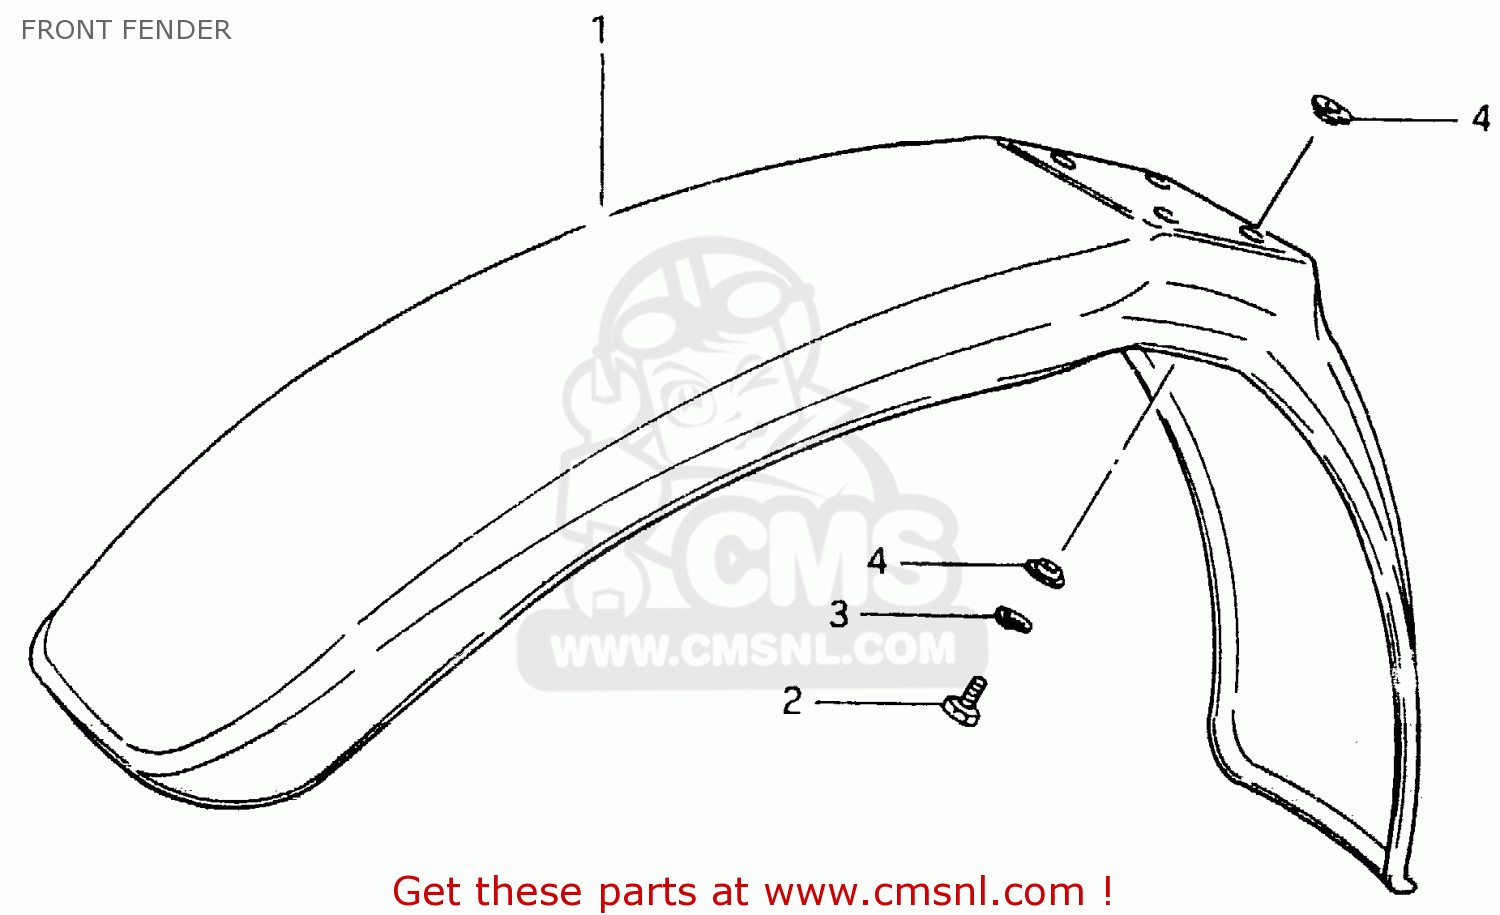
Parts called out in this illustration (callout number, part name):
1	FENDER,FR
2	BOLT, UPPER
3	LOCK WASHER
4	SPACER
